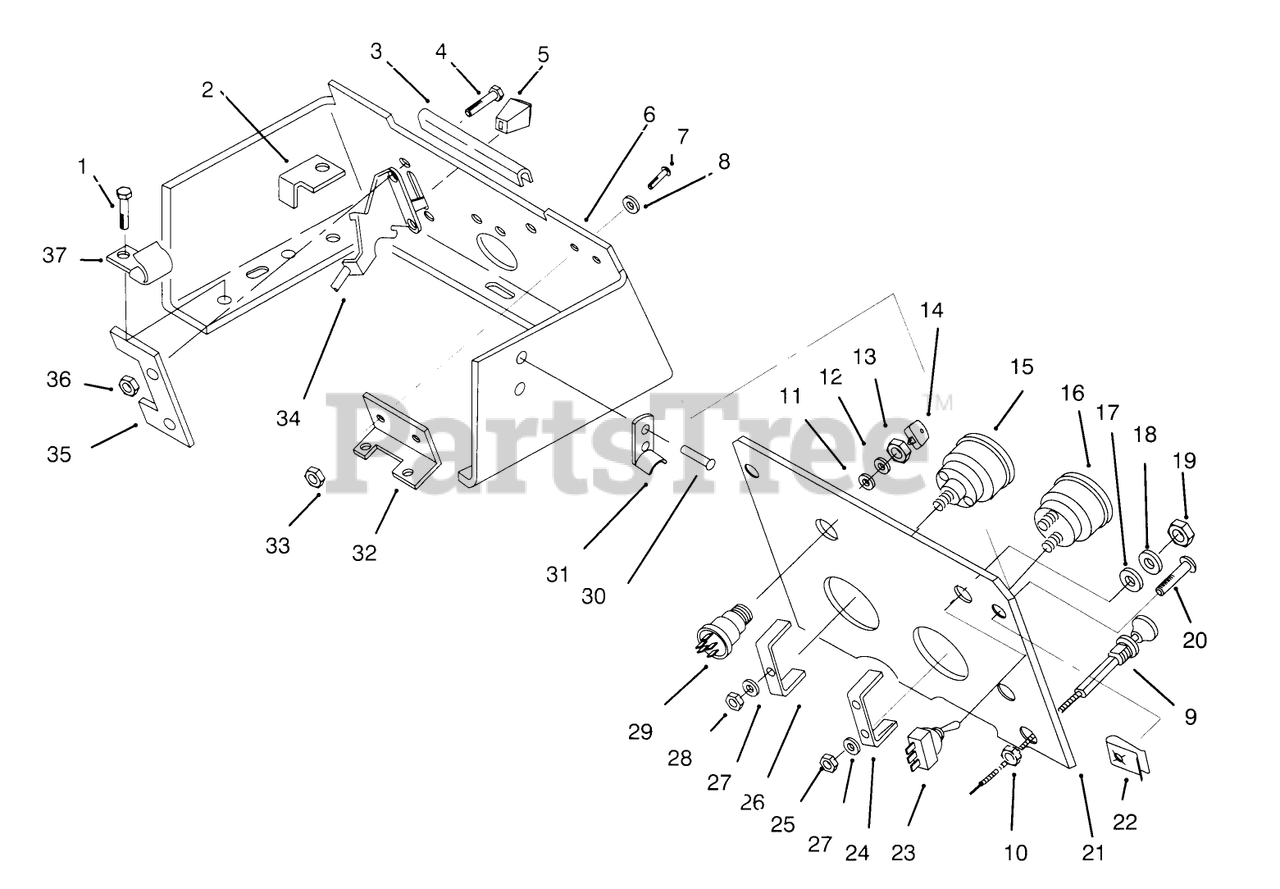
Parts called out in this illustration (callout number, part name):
2	STOP-PTO
3	EDGING-CONSOLE
6	CONSOLE *B
7	SCREW-PAN
8	Washer-Lock
9	CONTROL-CHOKE
10	NUT-HEX PALNUT
14	KEY-IGNITION
16	VOLTMETER
17	Washer
18	TAB-WASHER
19	*DISC**
20	SCREW-PPH
22	CLIP
23	SWITCH-LIGHTS
24	CLAMP-MOUNTING
25	HEX NUT 10-32 E.S. + + USE 3296-21 + +
26	CLAMP-HOUR METER
28	NUT-HEX
31	KEEPER-LATCH
32	BRACKET
34	CONTROL-THROTTLE
35	Washer
37	J-CLIP
